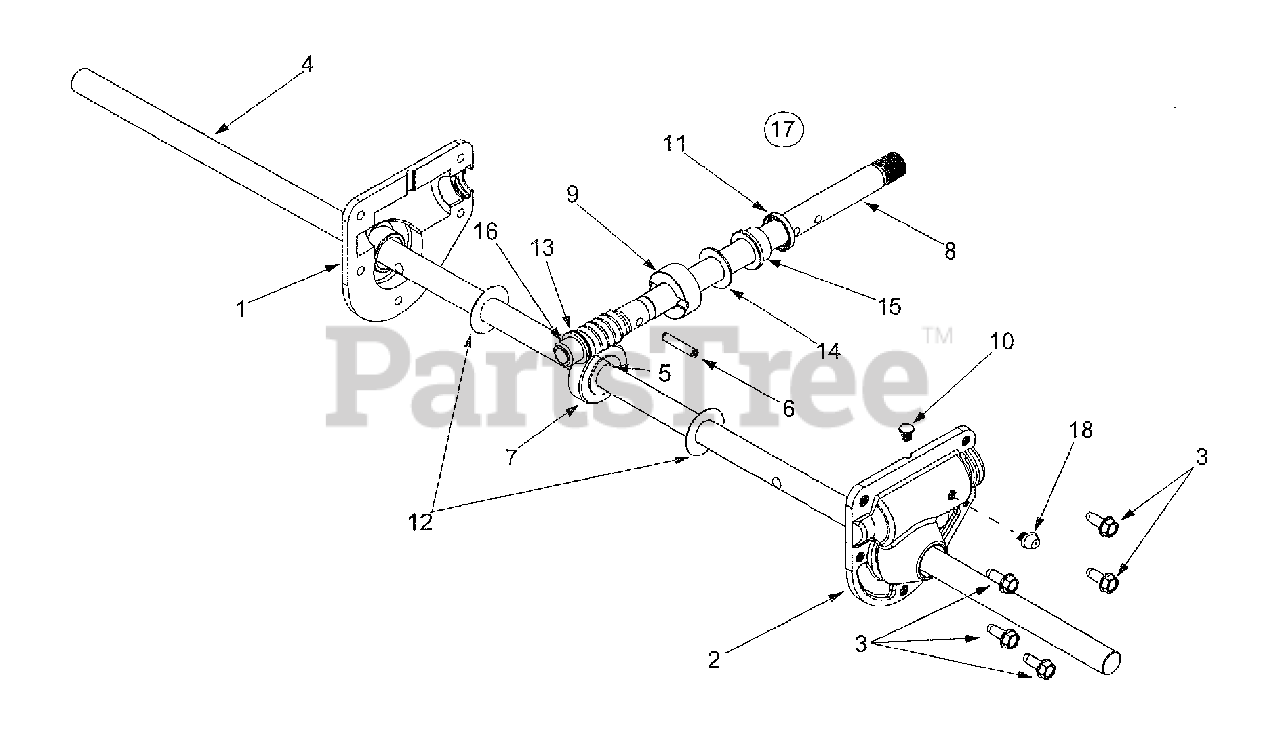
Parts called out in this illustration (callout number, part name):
1	RH Housing
2	LH Housing w/Fitting
3	Self Tapping Screw, 1/4-20 x .75
4	Spiral Axle 24"
5	Hi-Pro Key, 3/16 x 5/8
6	Spring Spiral Pin, .25 x 1.25
7	Worm Gear, 20-tooth
8	Worm Shaft
9	Thrust Collar
10	Grease Plug
11	Grease Seal
12	Flat Washer, .76 x 1.5 x .030
13	Flat Washer, .508 x 1.0 x .020
14	Flat Washer, .76 x 1.5 x .060
15	Flange Bearing, .75 x 1.0 x .59
16	Flange Bearing, .503 ID x .75 OD
17	Gear Assembly Complete, 24"
18	Grease Fitting, 3/16" Drive
